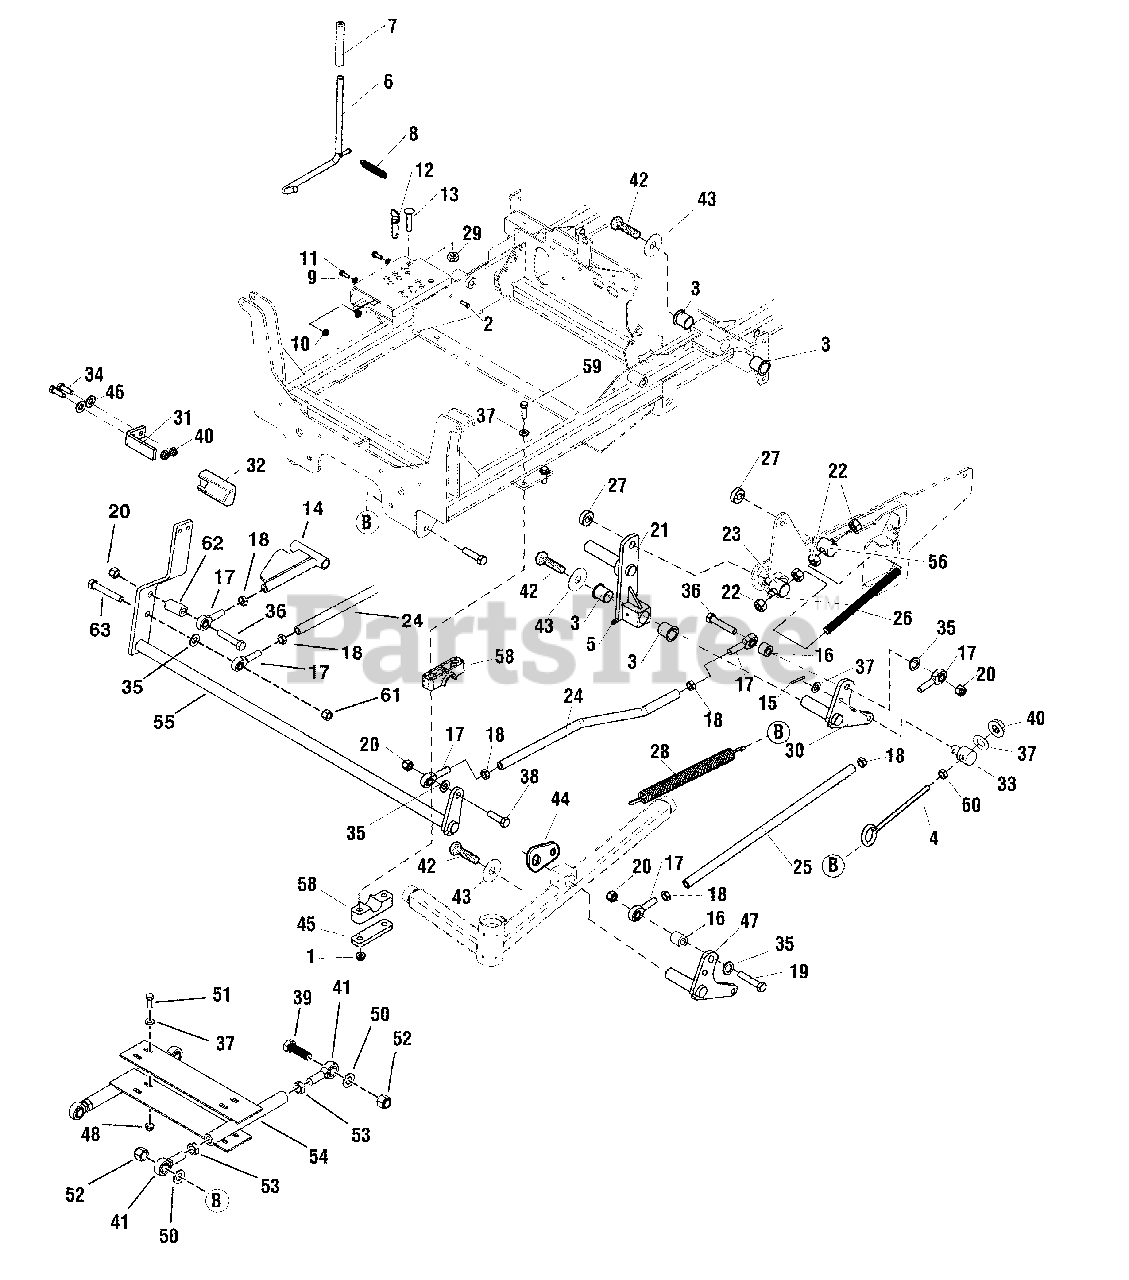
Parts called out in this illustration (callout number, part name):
1	NUT, 3/8-16 HEX NYLOCK FLANGE
2	PIN, CLEVIS, 1/4" x 7/8"
3	BUSHING, 1.00 X 1.13 X 1.38, PLASTIC
4	EYEBOLT, 3/2-16 X 8", 1" EYE
5	GREASE FITTING, 1/4-28 STRAIGHT
6	WELD, ROD DECK LIFT - BLK
7	GRIP, FOAM
8	SPRING, EXTENSION
9	WASHER, 1/4 SAE (5025154)
10	NUT, 1/4-20 HEX SERR. FLANGE
11	BOLT, 1/4-20 X 3/4" GD5 YZ
12	PIN, HITCH, 1/2 X 2.00 OAL, YP
13	BOLT, 3/8-16 X 2", CARRIAGE
14	WELD, DECK ADJUST LINK - RED
15	PIN, COTTER, 1/8" X 3/4
16	SPACER, .52 X 1.00 X .75
17	BALL JOINT, 1/2-20, MALE
18	NUT, 1/2-20 HEX JAM
19	BOLT, 1/2-13 X 2-3/4" GD5
20	NUT, 1/2-13 HEX NYLON LOCK
21	WELD, REAR LIFT, LH - BLK
22	NUT, 5/8-11 HEX
23	PIVOT, SPRING ROD
24	ROD, DECK LIFT BENT
25	ROD, DECK LIFT, OUTER
26	ROD, 5/8-11 X 9.00
27	COLLAR, 5/8" SPLIT
28	SPRING, DECK LIFT ASSIST
29	NUT, 3/8-16 HEX SIDE LOCK
30	WELD, DECK LIFT LEVER, LH - BLK
31	PEDAL, FOOT - BLK
32	RUBBER, FOOT PEDAL
33	ADJUSTER, DECK HANGER
34	BOLT, 3/8-16 X 1-1/4" GD5
35	WASHER, 1/2" SAE
36	BOLT, 1/2-13 X 3-1/2" GD5
37	WASHER, 3/8 SAE
38	BOLT, 1/2-13 X 1-3/4 GD5 YZ
39	BOLT, 3/4-16 X 2-1/2 YZ GD5
40	NUT, 3/8"-16 HEX NYLON LOCK
41	BALL JOINT, 3/4-16, MALE
42	BOLT, 3/8-16 x 3/4, GD5, YZ WITH PATCH
43	WASHER, .390 X 1.50 X .109, YZ
44	MOUNT, SPRING DECK LIFT - RED
45	PLATE, PIVOT BLOCK SUPPORT - BLK
46	WASHER, 3/8" GR9 FLAT
47	WELD, PIVOT DECK LIFT - LH - RED
48	NUT, 3/8-16 HEX SERRATED FLANGE
50	WASHER, 3/4 SAE
51	BOLT, 3/8-16 X 1" GD5 YZ
52	NUT, 3/4-16 HEX NYLON LOCK
53	NUT, 3/4-16 HEX JAM
54	WELD, DECK STABILIZER - BLK
55	WELD, DECK LIFT SHAFT - RED
56	PIVOT, SPRING ROD
57	WELD, PIVOT DECK LIFT - RH - RED
58	PIVOT BLOCK, PLASTIC
59	BOLT, 3/8-16 X 2-3/4 GD5 YZ
60	NUT, 3/8-16 HEX
61	NUT, 1/2-13 HEX SIDE LOCK
62	SPACER, .52 X 1.00 X 1.75
63	BOLT, 1/2-13 X 2-1/4" GD5
